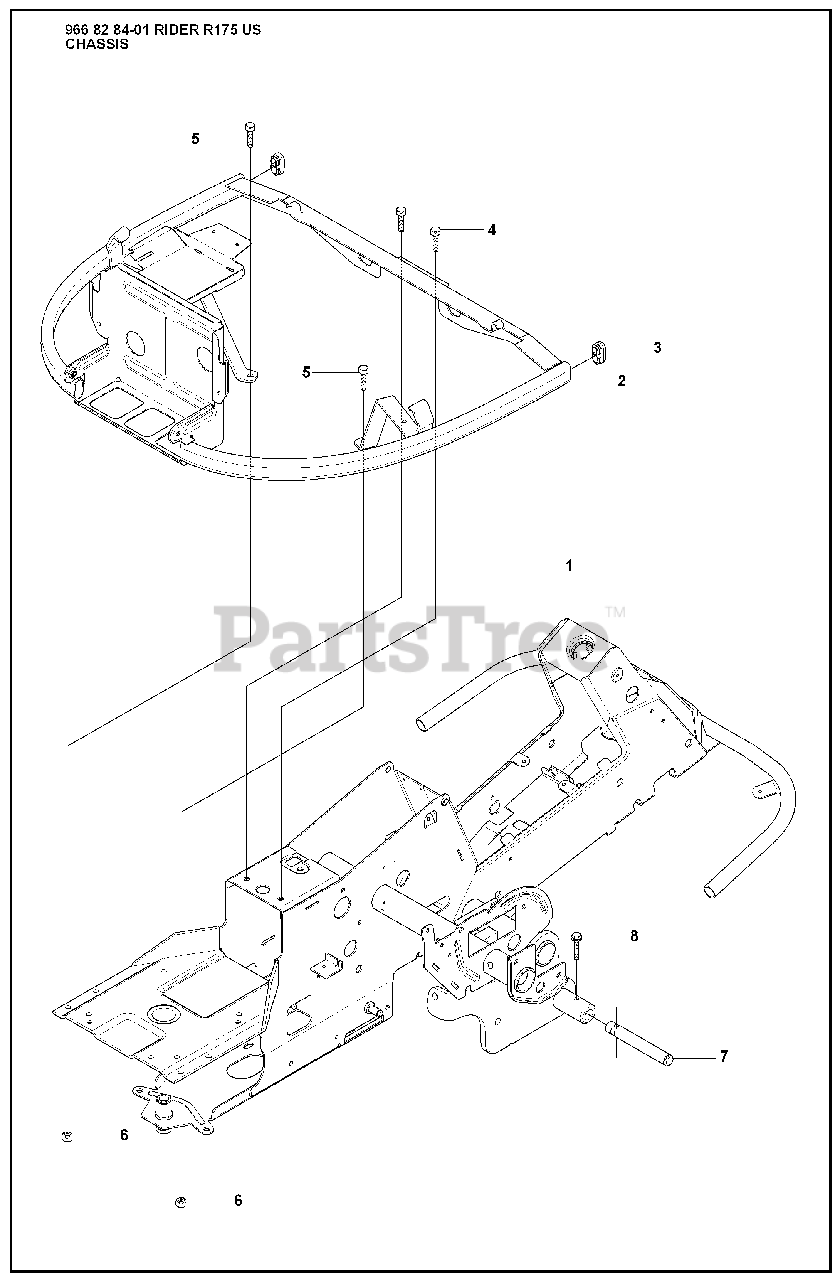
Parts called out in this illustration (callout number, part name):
2	ENGINE FRAME
6	LOCKNUT M8
8	BOLT FLANGE - M8X40\
